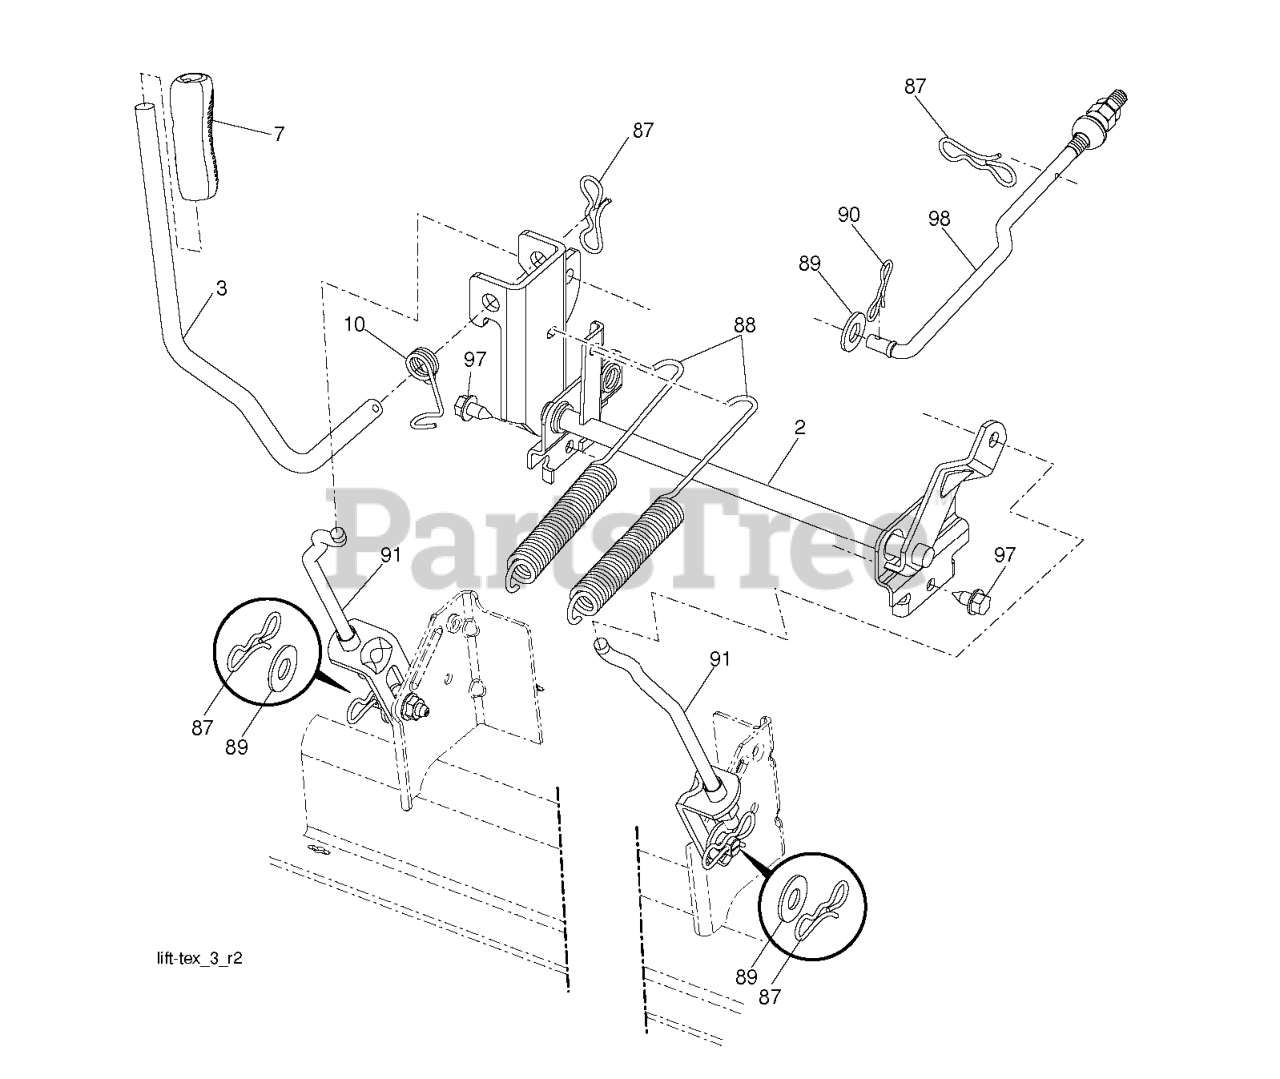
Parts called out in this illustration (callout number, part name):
2	SHAFT.ASM.CROSS.LIFT
3	LEVER.LIFT.HANDLE.GT
7	GRIP.HANDLE.LIFT.PVC.BLACK
10	SPRING.TORSION.LIFT.HANDLE
87	PIN.COTTER.7/16.BOW TI.
88	SPRING.LIFT.ASSIST.GT2
89	WASHER.CLEAR.ZINC
90	PIN.COTTER.5/16.BOW TI
91	LINK.ASM.LIFT.54"TG
97	SCREW, 3/8-16X3/4
98	LINK.ASM.SUSP.FRONT.MWR.10.5
